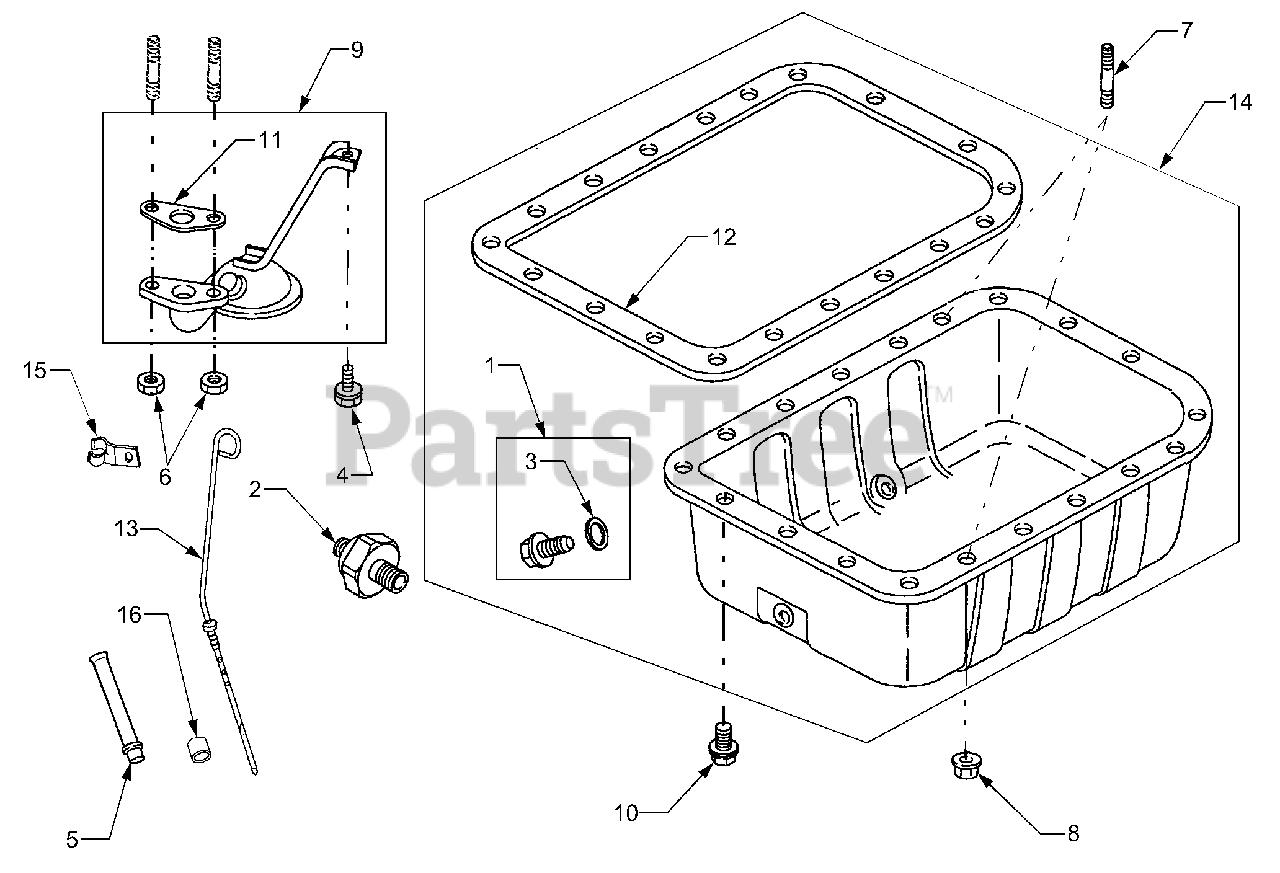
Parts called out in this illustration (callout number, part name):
1	Plug, Oil Drain 16mm
2	Switch, Oil Pressure
3	Washer, Sealing
4	Screw, Oil Pump Screen
5	Tube, Dipstick
6	Nut, Oil Pump Screen
7	Stud, Oil Pan
8	Nut, Oil Pan
9	Oil Pump Screen
10	Screw, Oil Pan
11	Gasket, Oil Pump Screen
12	Gasket, Oil Pan
14	Pan, Oil
15	Bracket, Support
16	Collar, Dipstick Tube
